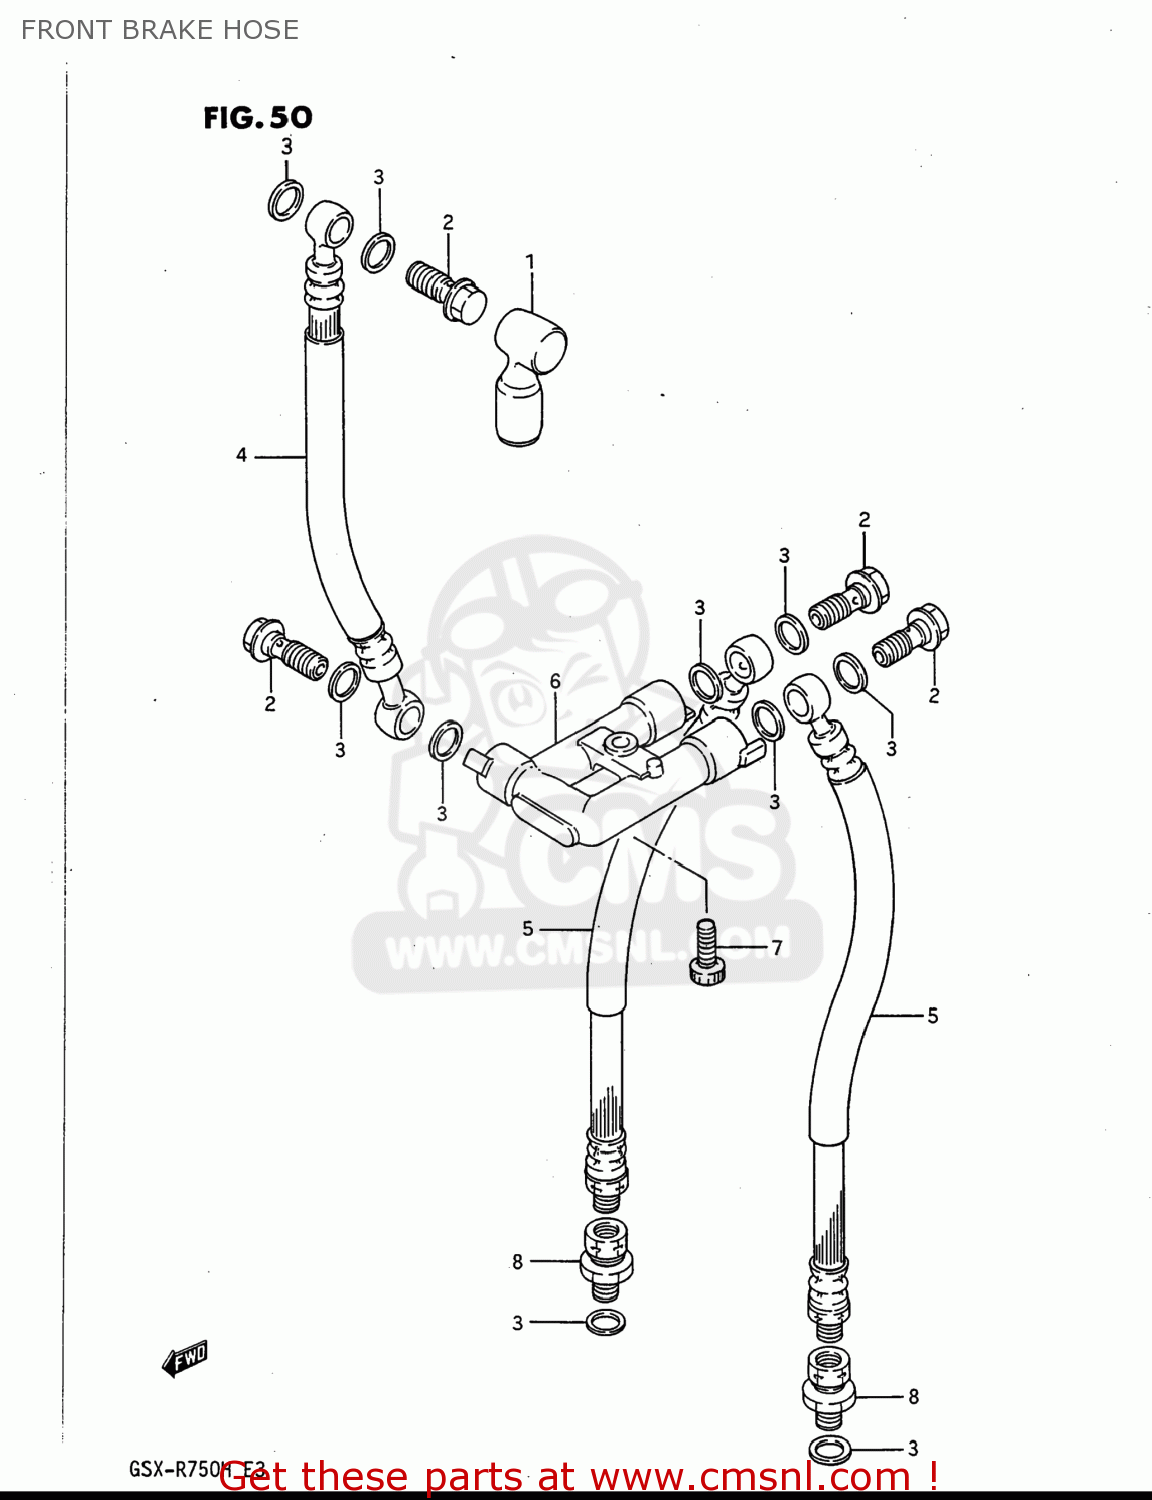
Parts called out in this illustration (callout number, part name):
1	BOOT,MASTER CYLINDER
2	BOLT UNION
3	WASHER(10X15X1.5)
4	HOSE,FRONT BRAKE
5	HOSE,FR BRAKE NO.2
6	JOINT,BRAKE HOSE
7	BOLT
8	ADAPTER,BRAKE HOSE
